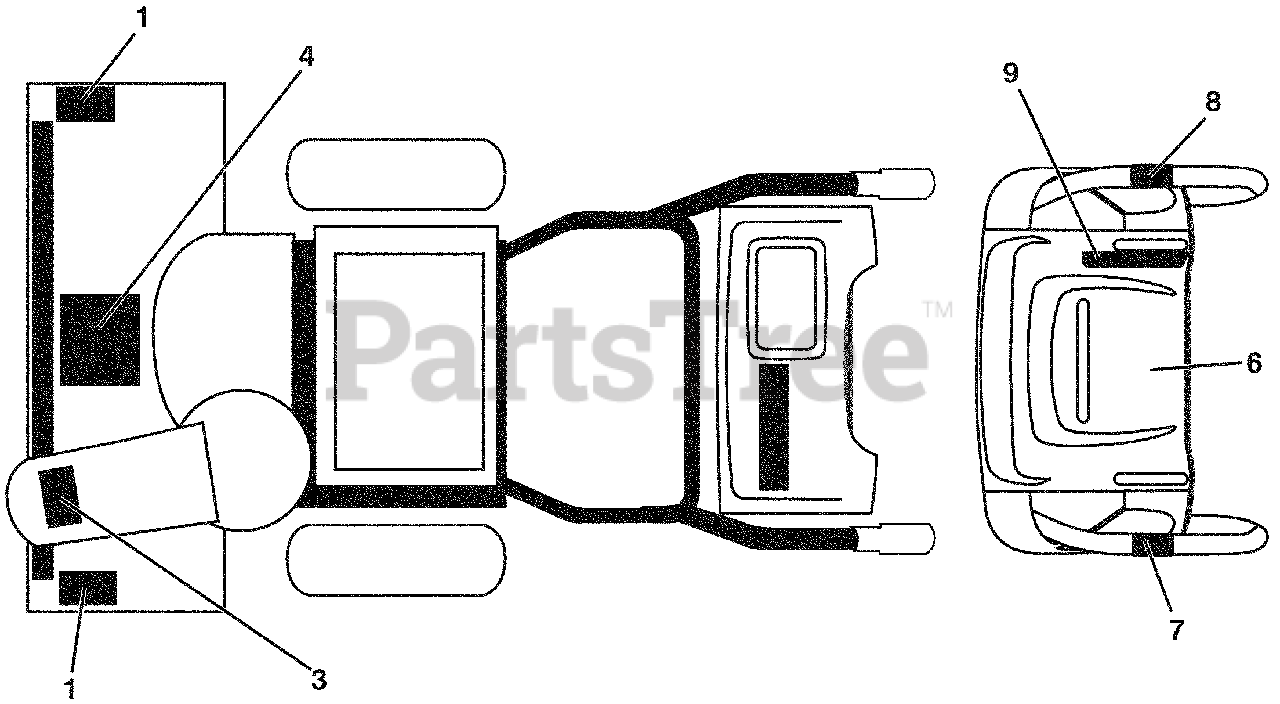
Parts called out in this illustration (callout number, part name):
1	DECAL, DANGER
3	DECAL, DANGER, DEFLECTOR
4	DECAL, DANGER
6	DECAL, INSTRUCTION
7	DECAL, TRACTION LEVER
8	DECAL, AUGER LEVER
9	DECAL, SPEED CONTROL
